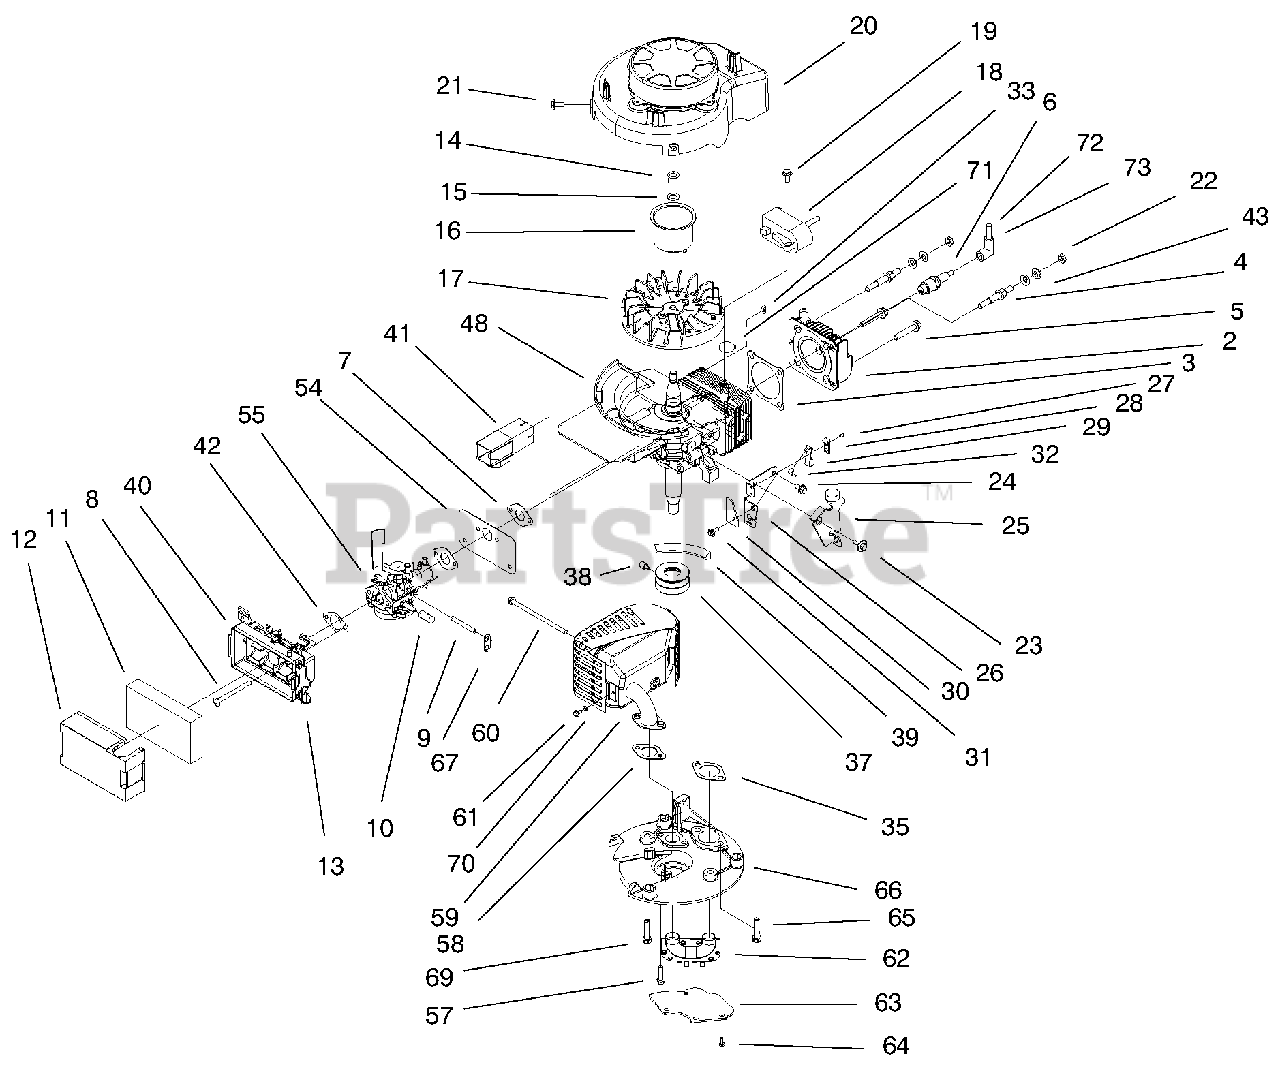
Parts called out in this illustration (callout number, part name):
3	Gasket-Head
6	Spark Plug
7	Intake Gasket
9	Primer Hose
11	Element-Air Filter
12	Cover-Air Filter
13	Retainer-Filter
15	Washer-Lock
16	Cup-Starter
17	Flywheel Machined Recoil
18	Ignition ASM
19	Screw-HWH
20	Shroud & Recoil ASM
21	Screw
22	Nut-Lock
23	Shoulder Screw Brake
24	Screw (Brake)
25	ASM-Brake Plate
26	Plate-Mount Brake
27	Rivet-Self Expand Plas
28	Strap-Insulation
29	Strap-Ground
30	Stop-Ground Strap
31	Screw-Thread Forming
32	Brake Switch Lead Wire
35	Gasket-Exhaust
37	Pulley Engine
38	Screw-Set
40	Air Filter Base ASM
42	Gasket-Filter Base
43	Washer-Lock
48	Short Block ASM Service
54	Heat Shield
55	Carburetor ASM
57	Screw-HWH
59	Muffler & Guard
62	Transfer Tube
63	Cover Plate
65	Screw-HH
66	Muffler Plate Machining
67	Retainer Hose
69	Screw-Hhd Washer
70	Washer-Lock
71	Tie Strap
72	High Tension Lead
73	Cover & Terminal
